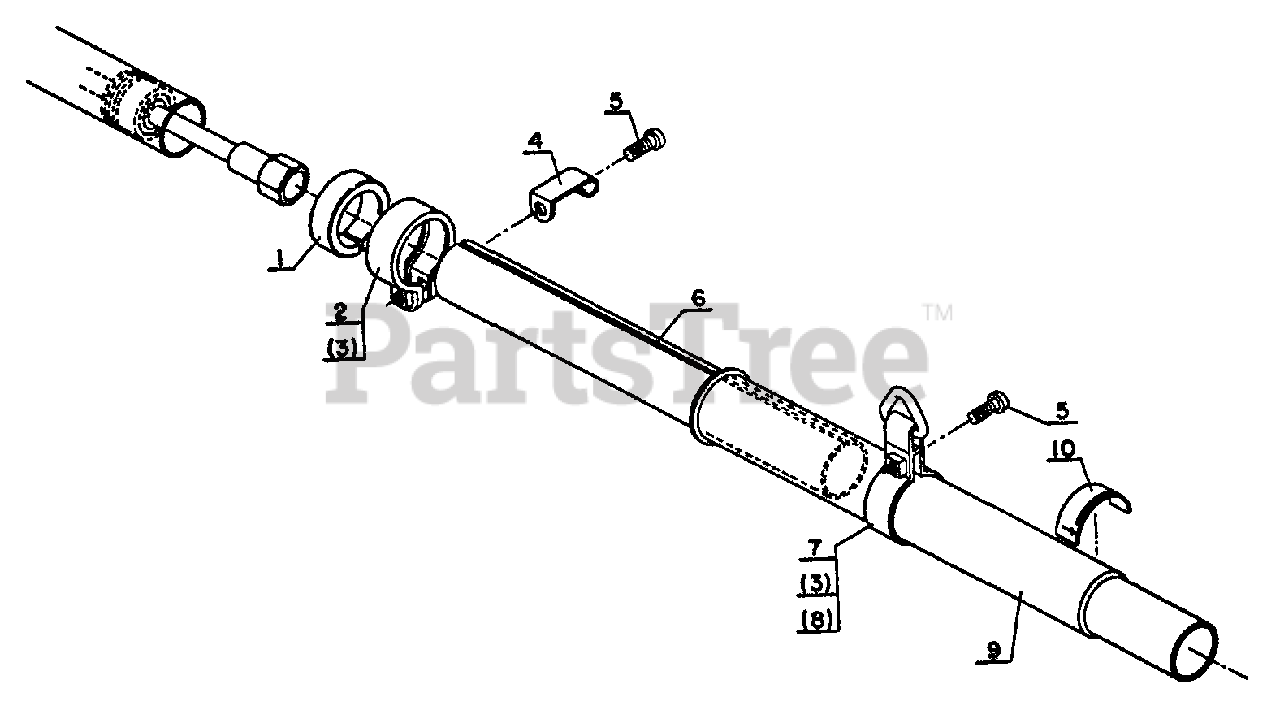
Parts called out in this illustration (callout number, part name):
1	SPACER
2	CLAMP
5	SCREW - 5X18
5	SCREW - 5X16
6	BUSHING
7	HANGER
9	PIPE, MAIN
10	LABEL - CAUTION
